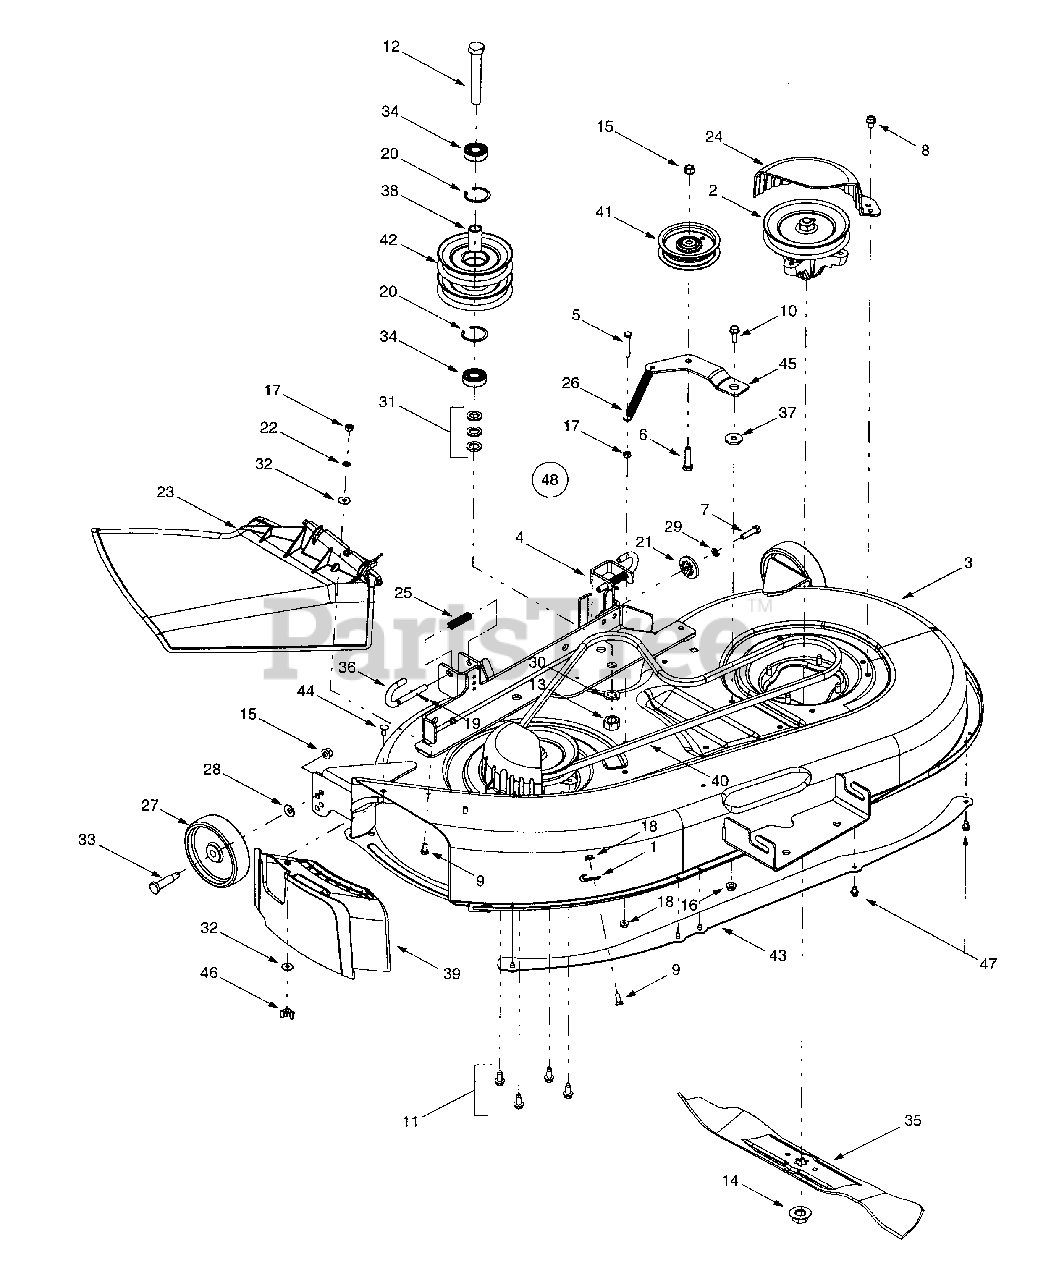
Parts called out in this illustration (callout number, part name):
1	Retainer Hook
2	Spindle Assembly, 5.75 Dia.
5	Hex Cap Screw, 1/4-20 x 1.75
6	Hex Cap Screw, 1/4-20 x 1.5
7	Hex Cap Screw, 5/16-18 x 1.25
8	Self-tapping Screw, 5/16-18 x .625
9	Hex Cap Screw, 1/4-20 x .62
10	Hex Head Washer Screw, 5/16-18 x .875
11	Self-tapping Screw, 5/16-18 x .75
12	Hex Cap Screw, 5/8-18 x .875
13	Hex Nut, 5/8-18
14	Hex Flange Nut, 5/8-18
15	Flange Lock Nut, 3/8-16
16	Flange Lock Nut, 5/16-18
17	Hex Nut, 1/4-20
18	Hex Flange Lock Nut, 1/4-20
19	Cotter Pin, 1/8 x 1.25
20	Internal Snap Ring
21	Deck Adjustment Gear
22	Push Nut. .25 x .5
23	Side Discharge Chute Assembly
24	Belt Cover
25	Compression Spring, .406 x .531 x 1.75
26	Extension Spring, .50 x 4.74
27	Deck Wheel, 5 x 1.38
28	Bell Washer, .401 x .87 x .063
29	Lock Washer, 5/16
30	Lock Washer, 5/8
31	Flat Washer, .64 x 1.0 x .12
32	Bell Washer, .265 x .75 x .062
33	Shoulder Screw, .498 x 1.53
34	Bearing, .625 x 1.574 x .470
35	Three-in-one Blade, Star Center, 21.23"
36	Deck Release Pin
37	Shoulder Spacer, .625 x .324
38	Spacer, .635 x .88 x 1.72
39	Mulch Plug
40	Deck Belt
41	Idler Pulley, 3.5
42	Double Pulley, 5.0
44	Carriage Screw, 1/4-20 x .62
46	Wing Nut, 1/4-20
47	Self-tapping Screw, 1/4-20 x.5
